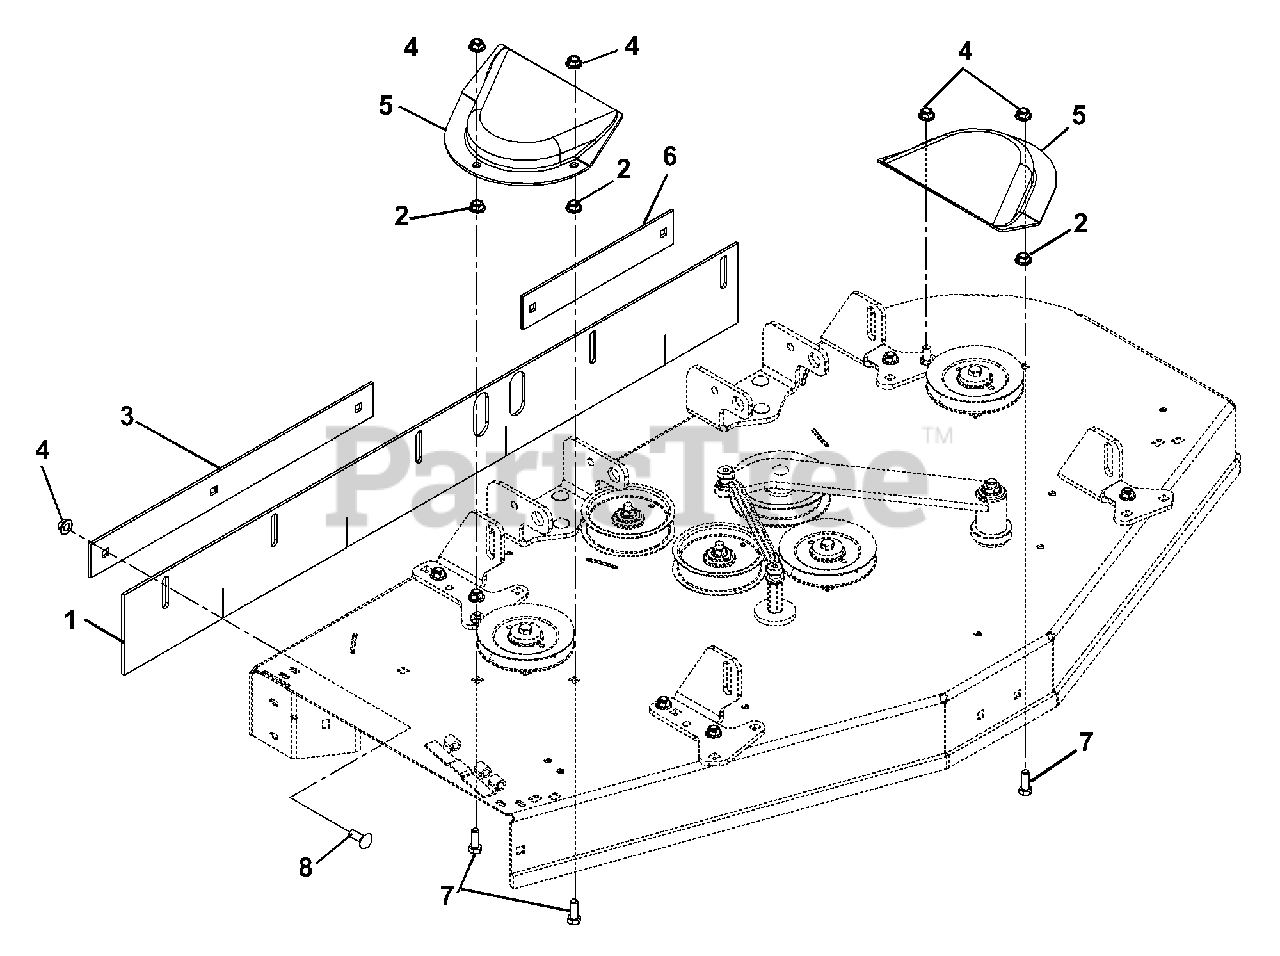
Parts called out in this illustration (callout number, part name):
1	STRIPER, RUBBER-48"
1	STRIPER, RUBBER-44"
2	@NUT-LK-TOP-FLG .38-16 YWZC
3	BAR, RETAINING STRIPER-44"
3	BAR, RETAINING STRIPER-48"
4	@NUT-LK-NYL-FLG .38-16 YWZC
6	BAR, LH RETAINER STRIPER
7	@BLT-HEX .38-16X1.00 GR5 YWZC
8	@BLT-RDHDSQNK .38-16X1.00 G5YZ
